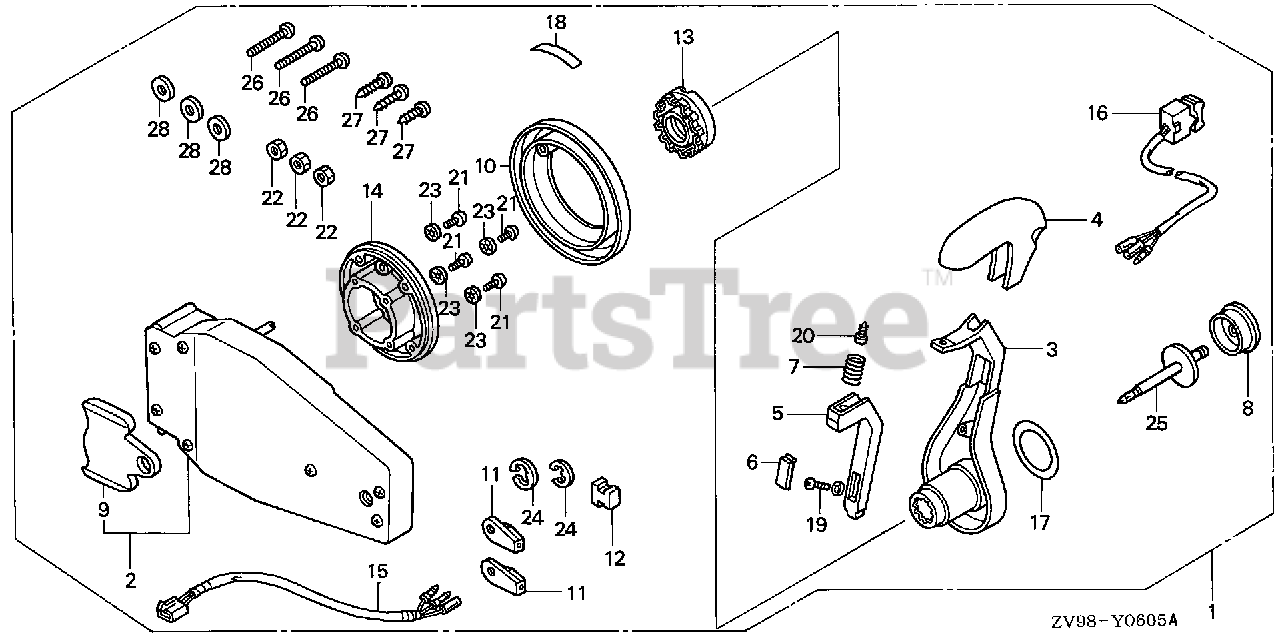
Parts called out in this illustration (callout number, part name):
1	BOX KIT, REMOTE CONTROL (FLUSH MOUNT)(L)
2	HOUSING ASSY., L. (INNER) (FLUSH MOUNT)
3	HANDLE, REMOTE CONTROL
4	COVER, GRIP
5	ARM, NEUTRAL LOCK
6	COVER, LOCK ARM
7	SPRING, NEUTRAL LOCK ARM
8	BUTTON, THROTTLE
9	PLATE, DWELL
10	COVER ASSY.
11	TERMINAL, CABLE
12	SPACER, CABLE CLAMP
13	HOLDER, NEUTRAL LOCK
14	BASE
15	SUB-HARNESS ASSY., POWER TRIM-TILT (C)
16	SWITCH ASSY., POWER TRIM-TILT (C)
17	MARK, HANDLE FLUSH MOUNT (HONDA MARINE)
17	MARK, HANDLE FLUSH MOUNT
18	MARK, FLUSH MOUNT
19	SCREW, PAN (5X16)
20	SCREW, TRUSS (4X12)
21	SCREW, PAN (5X30)
22	NUT, HEX. (6MM)
23	WASHER, LOCK (5MM)
24	E-RING (6MM)
25	SHAFT, THROTTLE BUTTON
26	SCREW, PAN (6X35)
27	SCREW, TAPPING (6X30)
28	WASHER, PLAIN (6MM)
